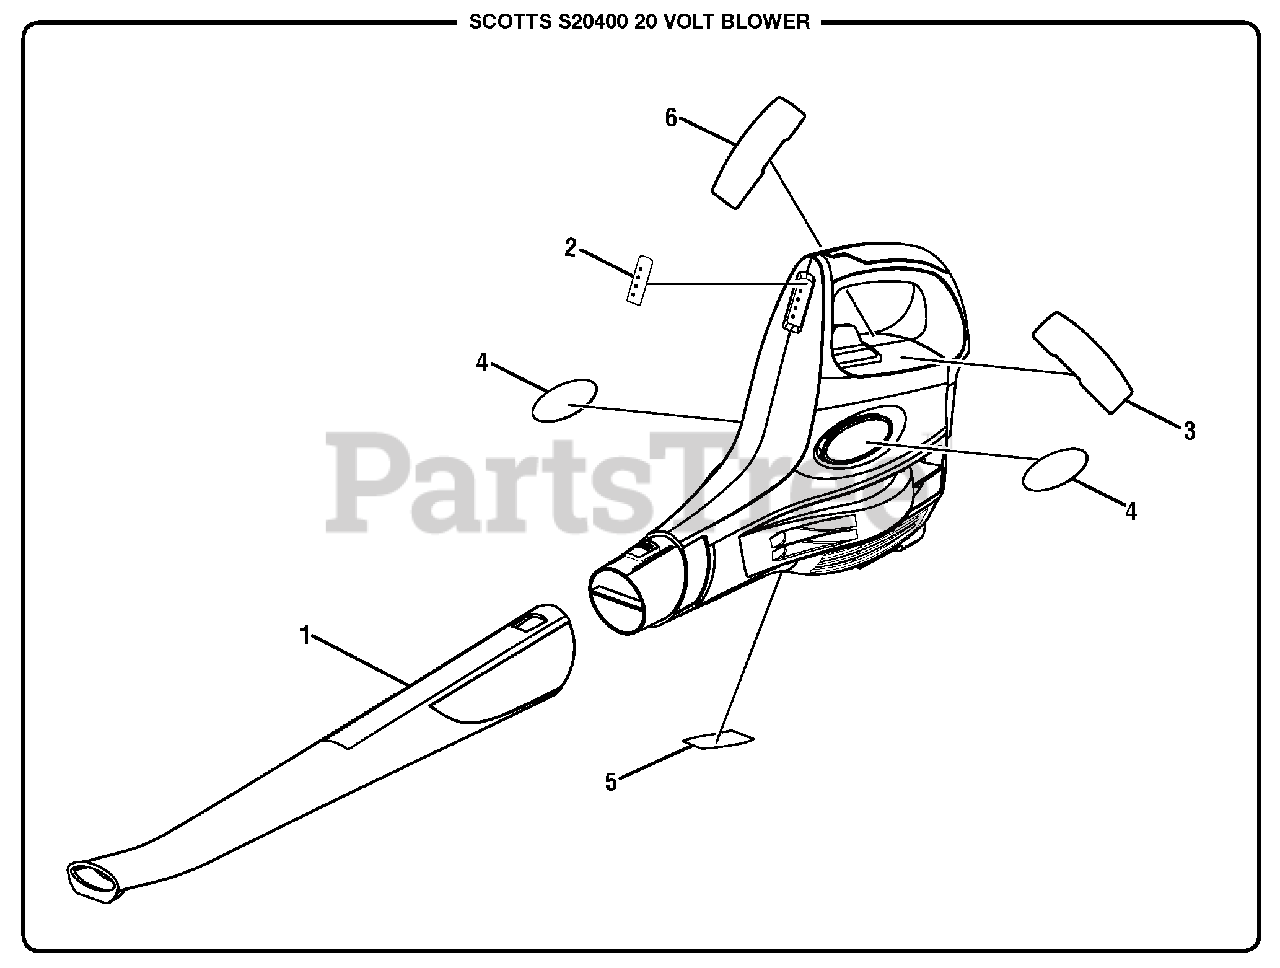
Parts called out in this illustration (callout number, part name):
1	Blower Tube
2	Fuel Guage Label
3	Warning Label (Fr/Sp)
4	Logo Label
5	Data Label
6	Warning Icon Label
